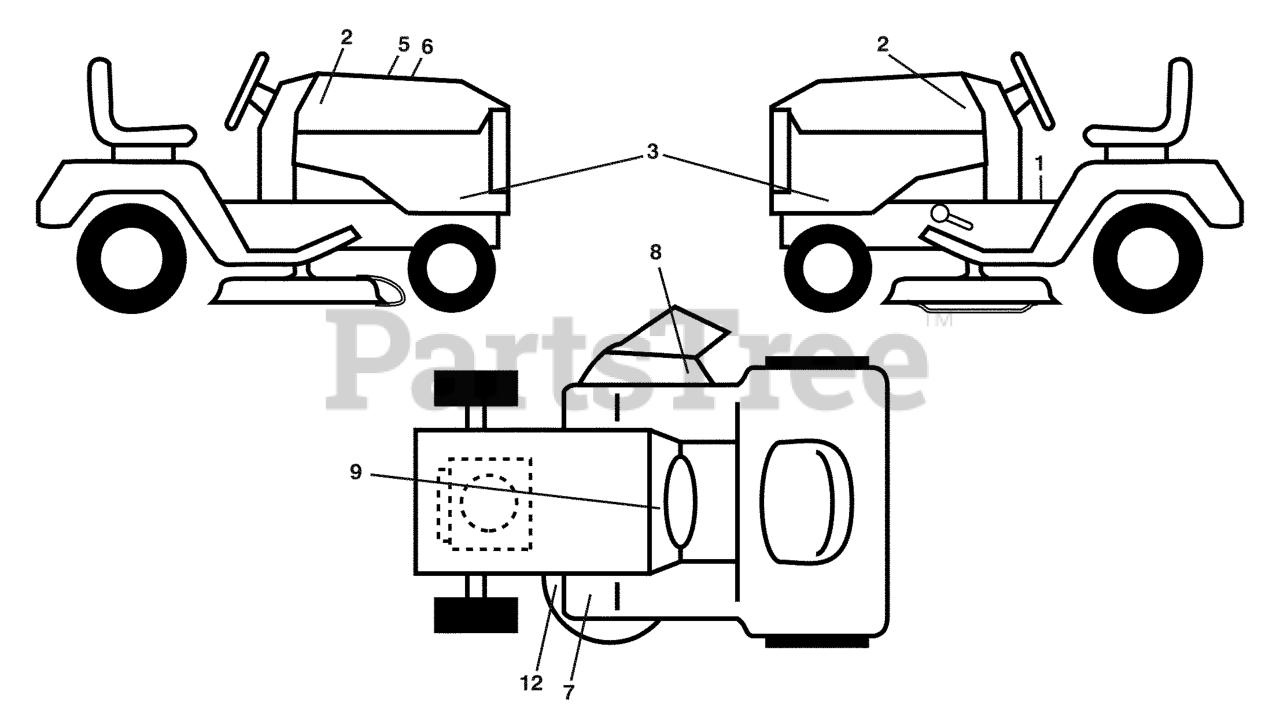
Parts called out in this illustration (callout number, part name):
1	DECAL.FENDER.WARNING.ENG
2	RP EMBLEM, HOOD
3	DECAL, EMBLEM PANEL SD
5	DECAL.WARNING.CUST.RESP.E85.
6	Decal, Replacement
7	DECAL.PEDAL.HUSQ.CROWN
8	DECAL.WARN.KEEP.HAND.AWAY
9	DECAL BTRY SYMBOLS
12	DECAL V BELT SCHEMATIC
